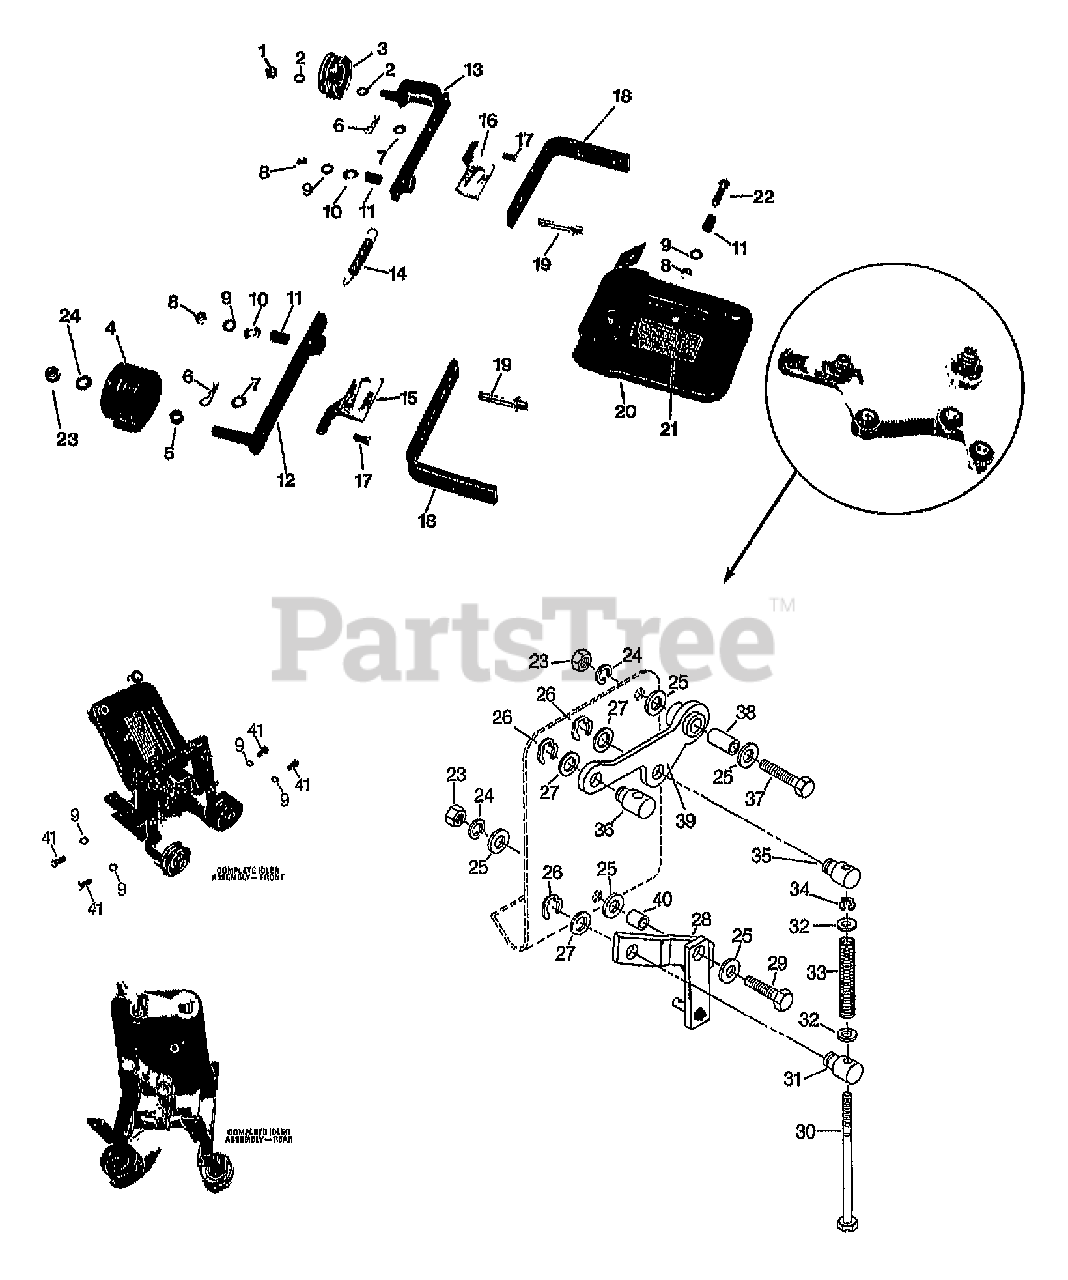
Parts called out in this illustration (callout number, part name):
1	NUT-H/LK 3/8-16
2	BUSHING-.54X.38X.08
3	IDLER-REV
4	PULLEY-FWD IDLER
5	BUSHING-.5X.375X.3
6	PIN-CLIP .08
7	WASHER-FLAT 1/4 SAE
8	NUT-HEX 5/16-18 ZP
9	WASHER-LK .312 ZP
10	WASHER-#.75X.32X.09 ZP
11	BUSHING-.438X.323X.712
12	ARM-IDLER FWD PNT
13	ASSM-IDLER REV @ DEPL
14	SPRING-.436 X 3.25
15	LINK-FWD
17	PIN-CLEVIS .375X.719 ZP
18	BAR-MTG PNT
19	STUD 5/16-18X2.145 ZP
20	BASE-SHIFTING W/DECAL (INCL. #50112 WARNING DECAL)
21	DECAL-BELT (WARNING INSTRUCTIONS ON BELTS/ PULLEYS)
22	SCR-HH 5/16-18X1.25 G5ZP
23	NUT-HEX 3/8-16 ZP
24	WASHER-LK .375 @ DEPL
25	SPACER-.88X.385X.09 ZP
26	RING-KLIP .500 ZINC
27	WASHER-#.88X.51X.063 ZP
28	BELLCRANK-WELDMENT
29	SCR-HH 3/8-16X1.25
30	SCR-HH 1/4-20X4.5 G5
31	PIVOT-SLIDE
32	WASHER # ZP (BETWEEN LOWER PIVOT & SPRING BETWEEN SPRING AND RETAINING RING)
33	SPRING-.52 X 3
34	RING-KLIP 5304-25
35	PIVOT-THREADED
36	PIVOT-ROD
37	SCR-HXSKT 1/4-20X.625
38	BUSHING-.5X.38X.815 (REPLACED BY #9060)
39	KIT-RODCRANK (REPLACED BY #20719)
40	BUSHING-.5X.38X.4
41	SCR-HH 5/16-18X1.0 G5 ZP
